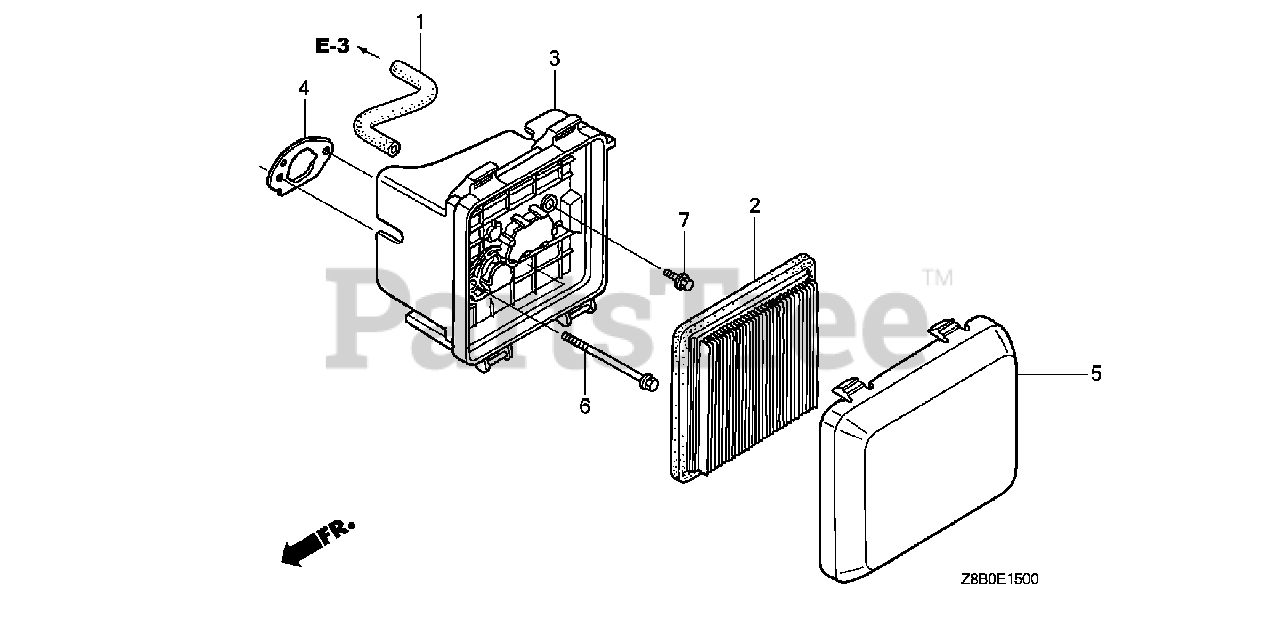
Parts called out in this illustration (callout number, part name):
1	TUBE, BREATHER
2	ELEMENT, AIR CLEANER
3	CASE ASSY., AIR CLEANER
4	GASKET, AIR CLEANER
5	COVER, AIR CLEANER
6	BOLT, FLANGE (6X86) (CT200)
6	BOLT, FLANGE (6X85) (CT200)
7	BOLT, FLANGE (6X14)
